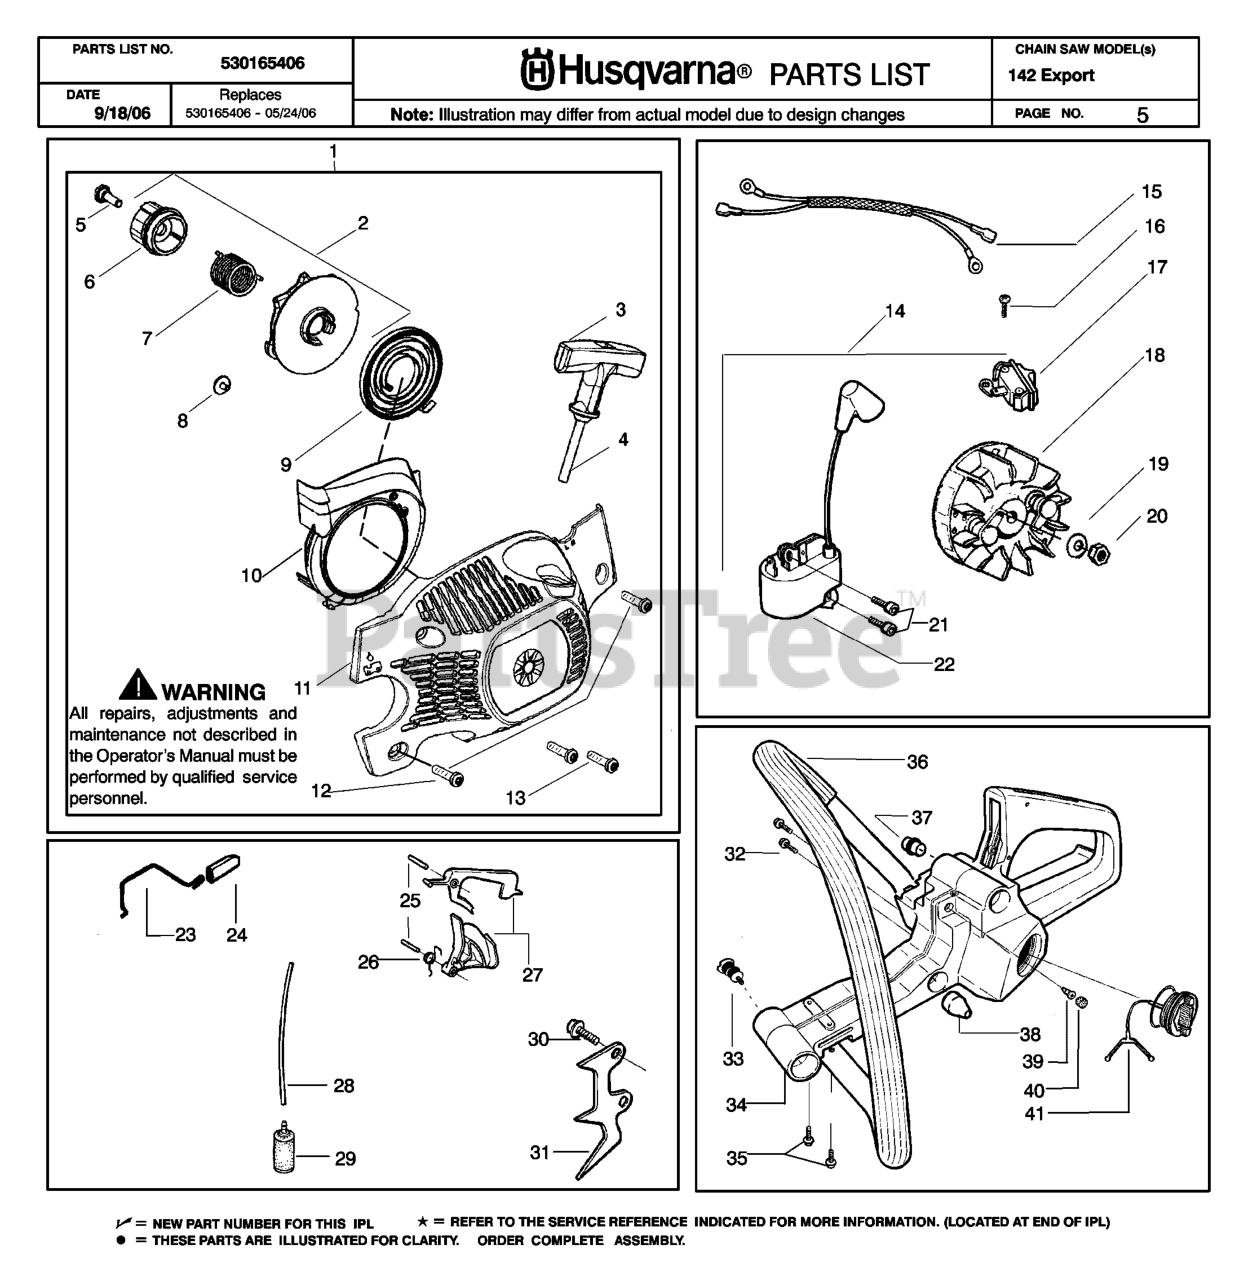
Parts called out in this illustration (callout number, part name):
1	KIT FAN HSG & STARTER EPS
2	KIT EPS STARTER
3	STARTER HANDLE GRAY
5	SCREW SHOULDER
6	HUB STARTER EPS
7	SPRING EPS
9	SPRING STARTER
10	BAFFLE AIR
11	HOUSING FAN W/ EYELET
13	SCREW,STRTR CVR 36/41
14	KIT EPS IGNITION
15	LEAD WIRE ASSY
17	SWITCH ON/OFF
18	FLYWHEEL ASSY
19	WASHER-FLYWHEEL
20	NUT-FLYWHEEL
22	IGNITION MODULE
23	THROTTLE SHAFT 36/41
24	THROTTLE ACTUATOR 36/41
25	PIN,TRIGGER 36/41
26	TRIGGER SPRING 36/41
27	THROTTLE TRIGGER-KIT
28	HOSE. FUEL
29	FUEL PICK-UP
31	SPIKE 36/41
36	HANDLE FRONT
37	FRONT HANDLE ISOLATOR
38	SHOCK MOUNT(X2) 36/41
39	VALVE-CHECK (DUCKBILL)
40	BRONZE PLUG
41	FUEL CAP KIT
